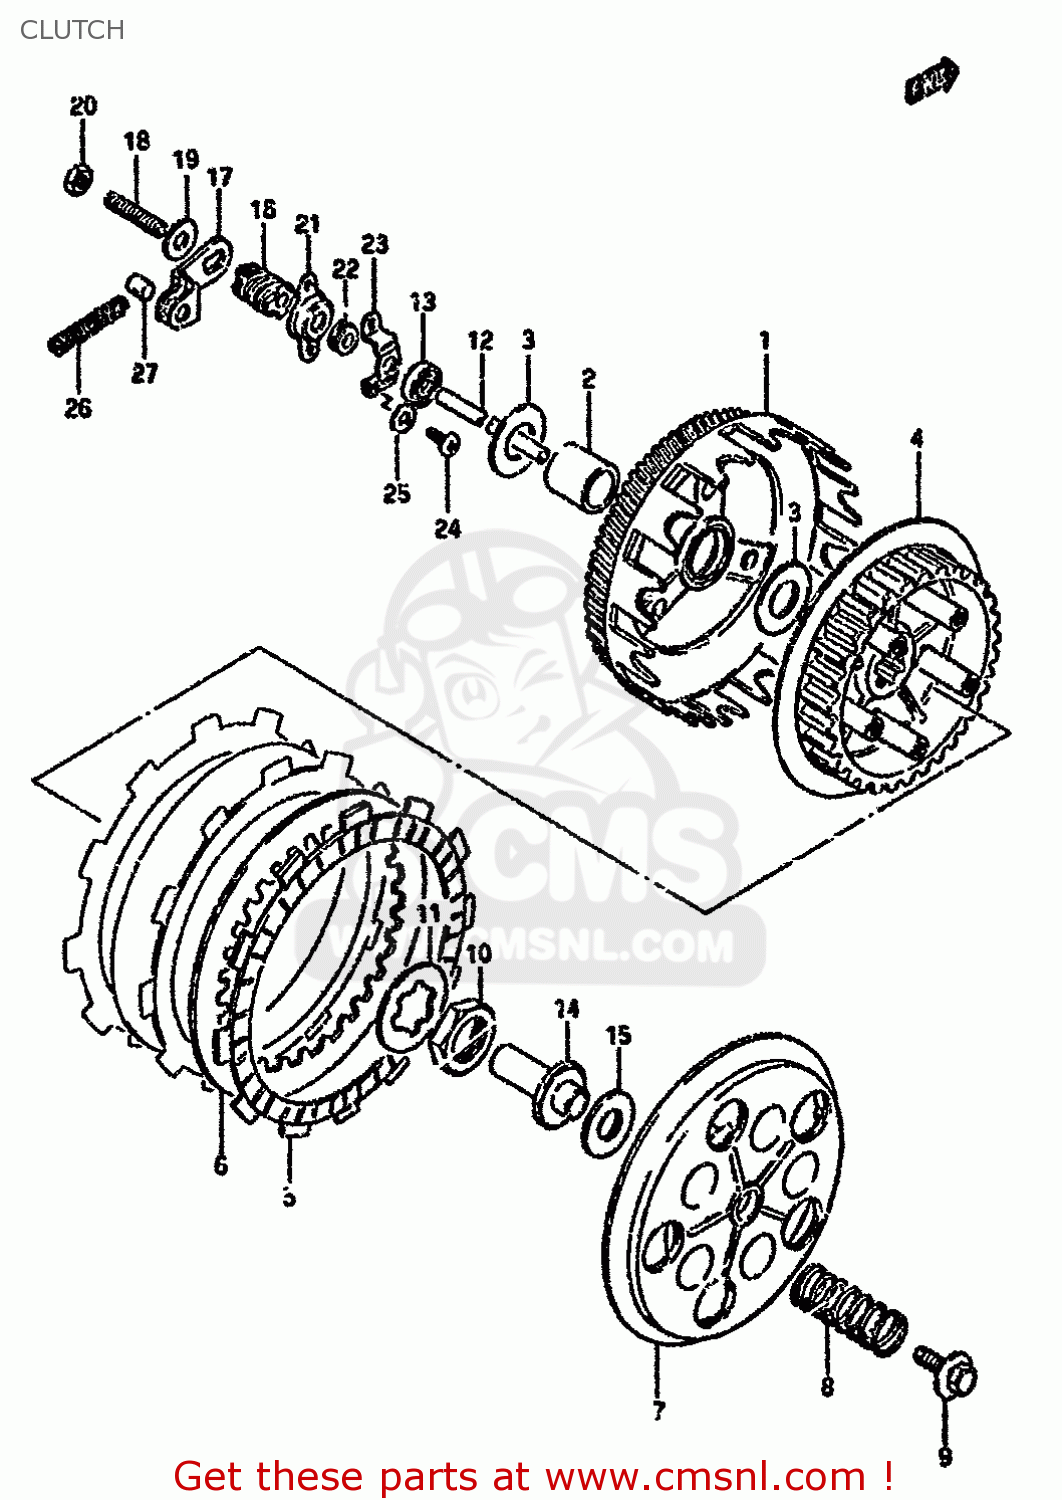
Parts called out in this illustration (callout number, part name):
1	GEAR ASSY,PRIMARY DRIVEN
2	SPACER(17X22X28.5)
3	WASHER
4	HUB,CLUTCH SLEEVE
5	PLATE,CLUTCH DRIVE(T:3.0) (NAS)
6	PLATE,CLUTCH DRIVEN (NAS)
7	DISC,CLUTCH PRESSURE
8	SPRING
9	BOLT 5X16
10	NUT
11	WASHER,LOCK
12	ROD,CLUTCH PUSH
13	SEAL,OIL(5.5X16X8)
14	PIECE,CLUTCH PUSH
15	BEARING(10X22X2.8)
16	SCREW,CLUTCH RELEASE
17	ARM,CLUTCH RELEASE
18	SCREW(6X25)
19	WASHER(6.5X20X1.6)
20	NUT
21	COVER,CLUTCH RELEASE SCREW
22	SEAL,DUST(5.3X13X5)
23	HOLDER,DUST SEAL
24	SCREW
25	WASHER
26	SPRING
27	HOOK,CLUTCH RELEASE SCREW ARM
